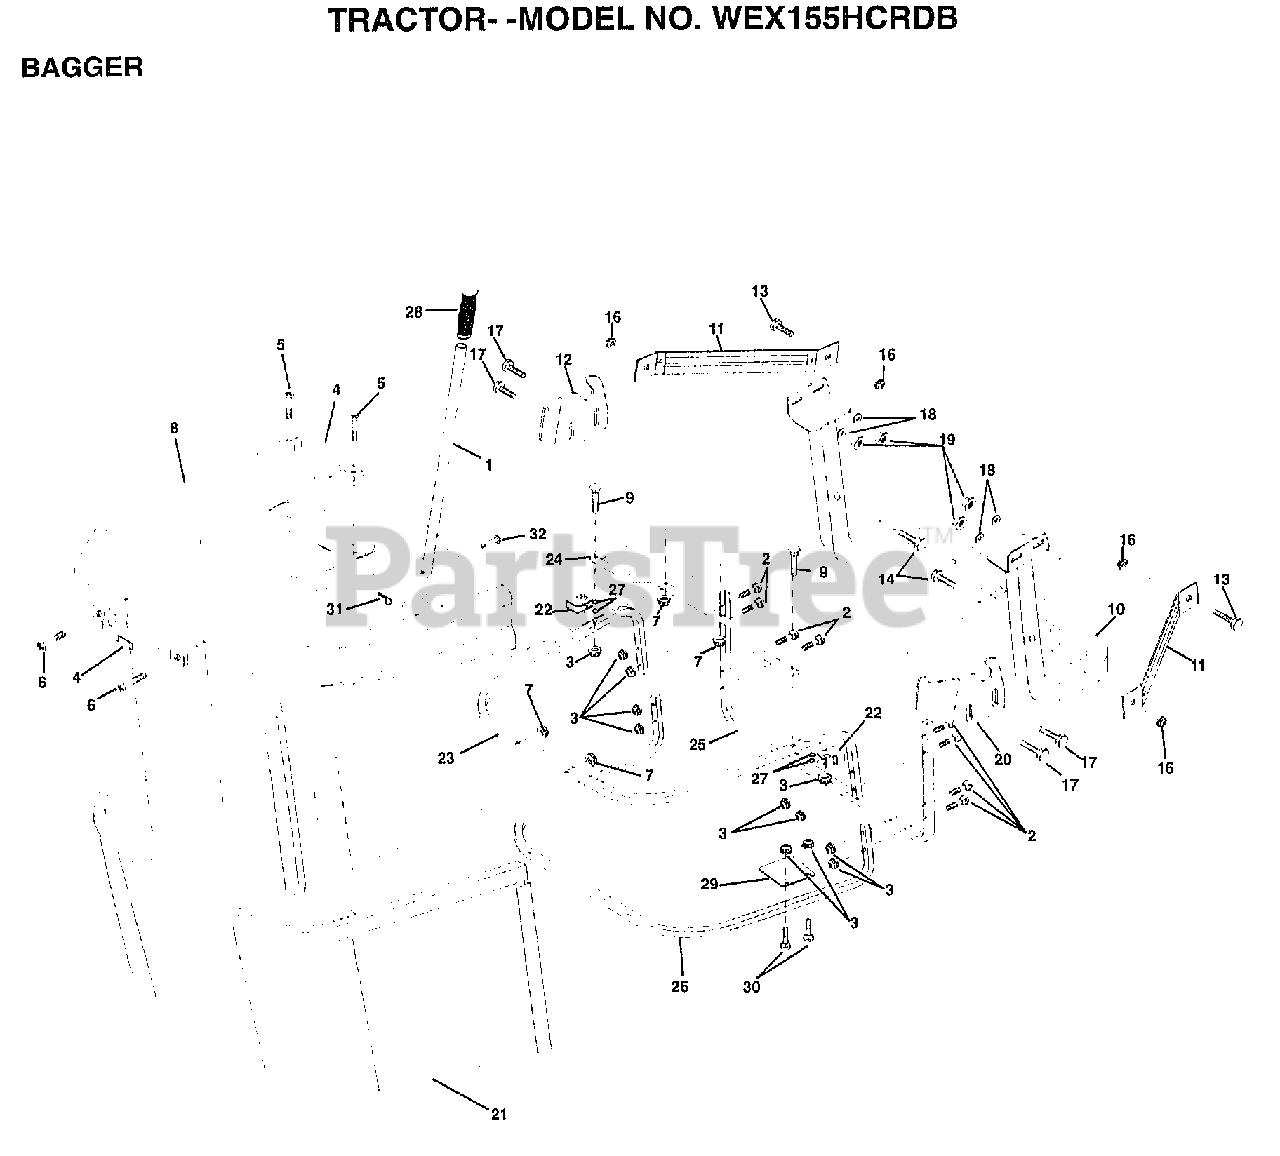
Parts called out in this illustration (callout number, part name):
1	TUBE.HDLE.BAG.CRD
2	BOLT.CARRIAGE.1/4-20X2.0
4	HANDLE.GRAB.BLACK.
5	"SCREW,PAN.HEAD"
7	NUT.WIZ.LOCK
8	COVER.BAGGER.CRD
9	BOLT CARRIAGE
10	SUPT.ASM.WLDMNT.BAG.CRD
11	BRKT.SUPT.UPPER.BAG.CRD
12	BRKT.PIVOT.BAG.LH.CRD
13	BOLT
14	BOLT.HEX.3/8-16X2-1/2
17	BOLT
18	WASHER
19	NUT
20	"BRKT.PIVOT.BAG,RH.CRD"
21	BAG.ASM.CRD
22	BRKT.SIDE.BAG.CRD
23	TUBE.UPPER.BAG.CRD
24	TUBE.PIVOT.BAG.CRD
25	TUBE.FT.BAG.CRD
26	TUBE.LOWER.BAG.CRD.
27	GROMMET.EXTRUDED
28	GRIP.HANDLE.BLACK
29	PLATE.STOP.BAG.HDLE.CRD
30	BOLT.CARRIAGE
31	RETAINER M
32	RIVET.DRILL.1.75
